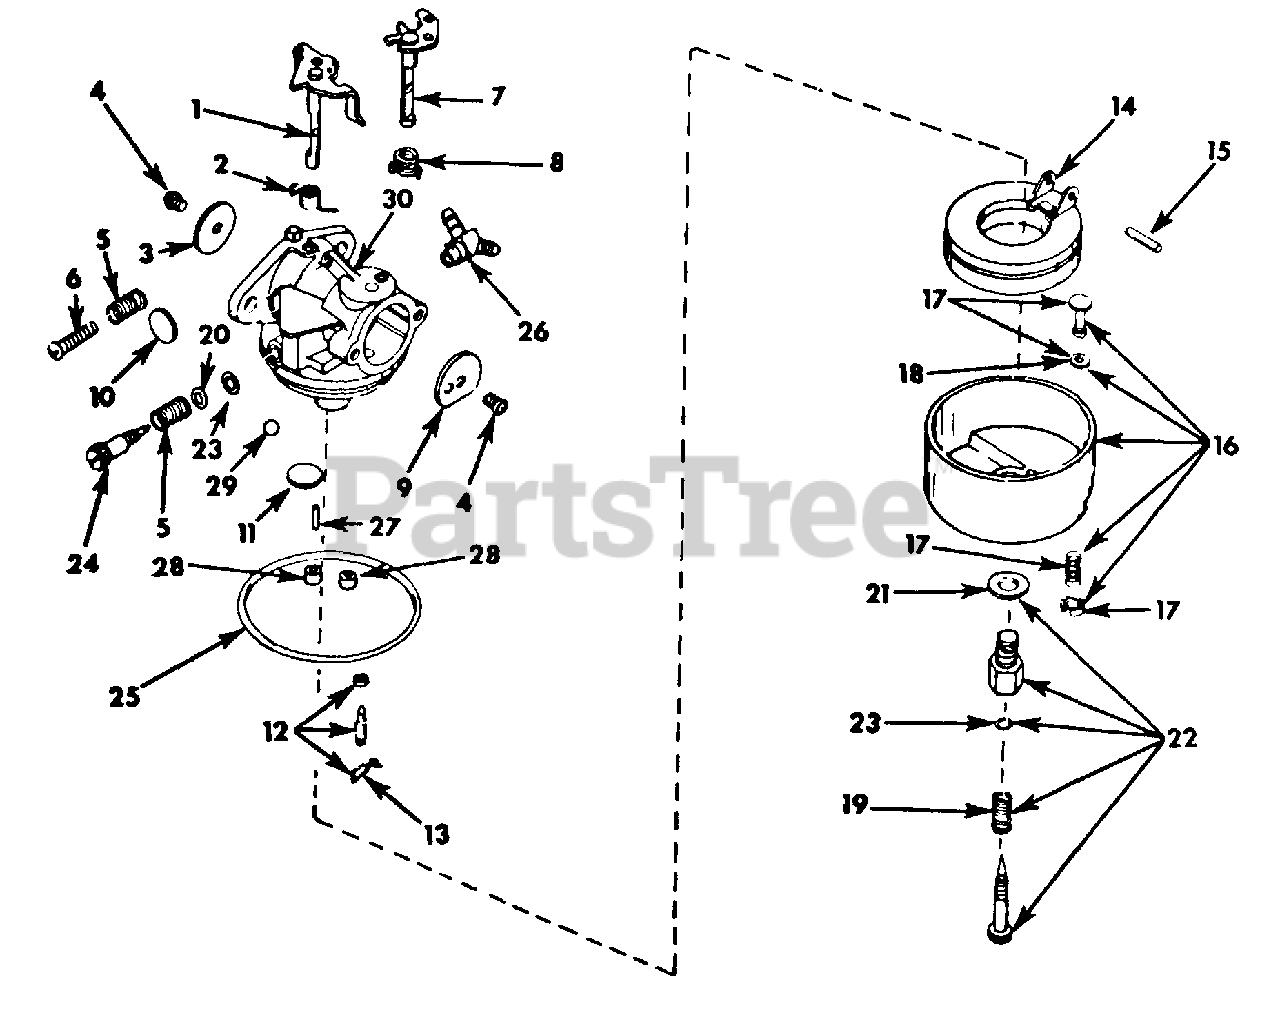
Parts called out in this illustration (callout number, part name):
1	SHAFT AND LEVER ASSY, THROTTLE
2	SPRING, THROTTLE RETURN
3	SHUTTER, THROTTLE
4	SCREW, 4-40 X 3/16 RD-HD
5	SPRING, IDLE REGULATING SCREW
6	SCREW, 8-32 X 3/4 C-2 SLT-RD-HD MACH
7	SHAFT AND LEVER ASSY, CHOKE
8	SPRING, CHOKE RETURN
9	SHUTTER, CHOKE
10	PLUG, WELCH
11	PLUG, WELCH
12	NEEDLE SEAT CLIP ASSY, INLET
13	CLIP, INLET NEEDLE
14	FLOAT, CARBURETOR
15	SPIN, FLOAT
16	BOWL AND DRAIN ASSY, FLOAT
17	DRAIN ASSY, BOWL
18	GASKET, DRAIN PLUNGER
19	SPRING, MAIN ADJUSTMENT SCREW
21	GASKET, BOWL-TO-BODY
22	SCREW ASSY, MAIN ADJ
23	O-RING, ADJUSTMENT SCREW
24	SCREW, IDLE ADJUSTMENT
25	GASKET, BOWL-TO-BODY
26	FITTING, FUEL INLET TEE
27	PIN
28	PLUG, CUP
29	BALL, ALUMINUM
